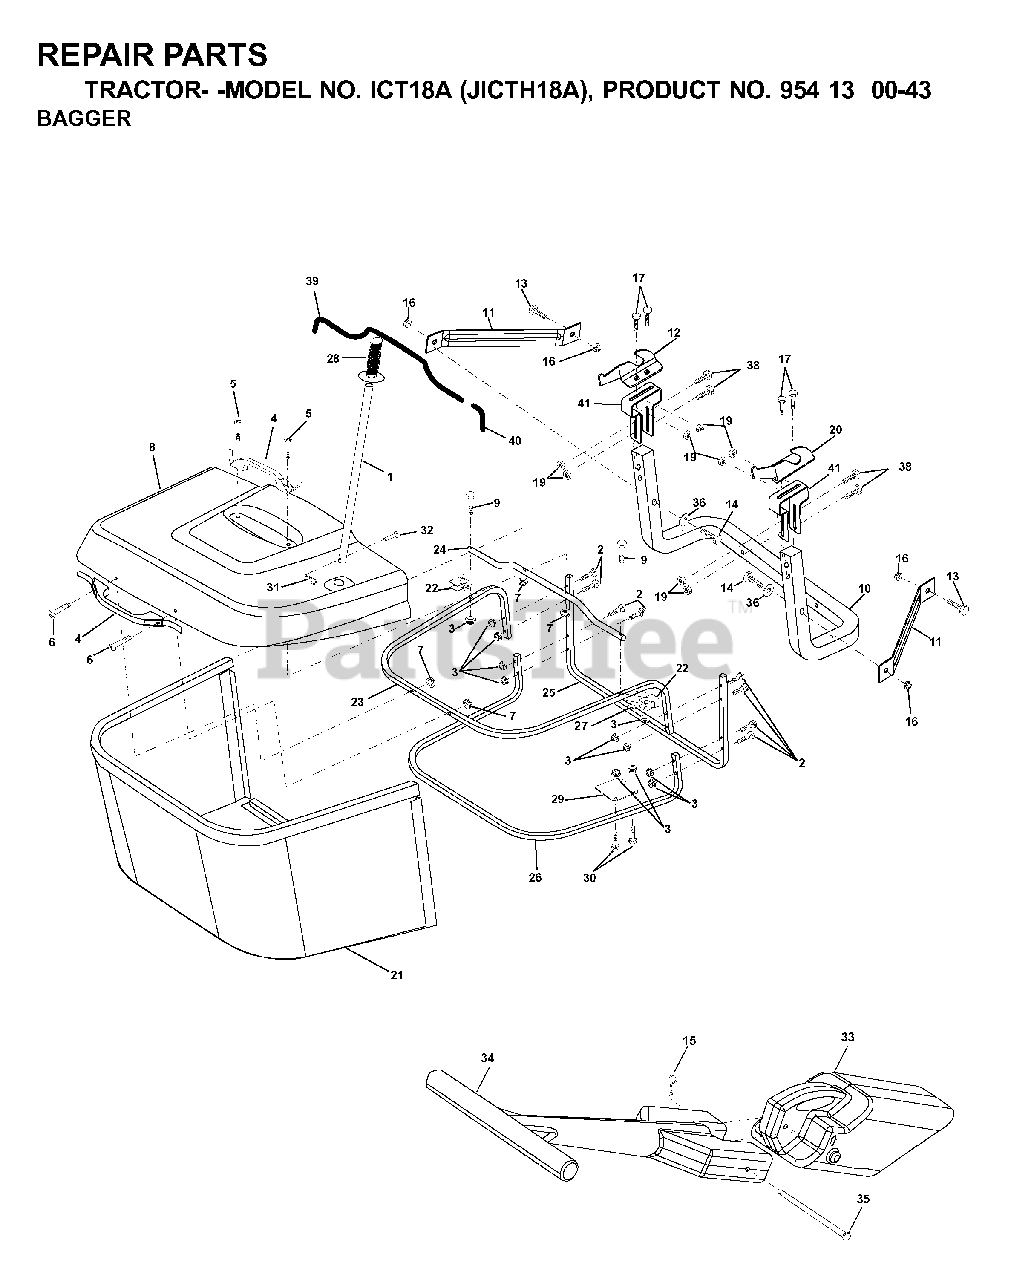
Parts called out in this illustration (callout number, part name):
1	TUBE HANDLE
3	NUT T
5	SCREW.PAN.HEAD
10	TUBE
11	BRACKET
15	RETAINER-SPRNG RB
16	NUT LOCK FLG 3/8-16 UNC
17	BOLT
18	WASHER M
19	NUT.71038.31-18.HEX.NYLOCK
20	BRACKET
21	BAG
22	BRACKET
23	TUBE
24	TUBE
26	TUBE
28	GRIP.HANDLE.BLACK
31	RETAINER M
32	RIVET,DRILLED
33	MULCH PLUG, CTH150
35	PIN
36	WASHER
38	BOLT.5/16-18X2.5
39	TRIM
40	TRIM
41	BRKT, BAGGER
